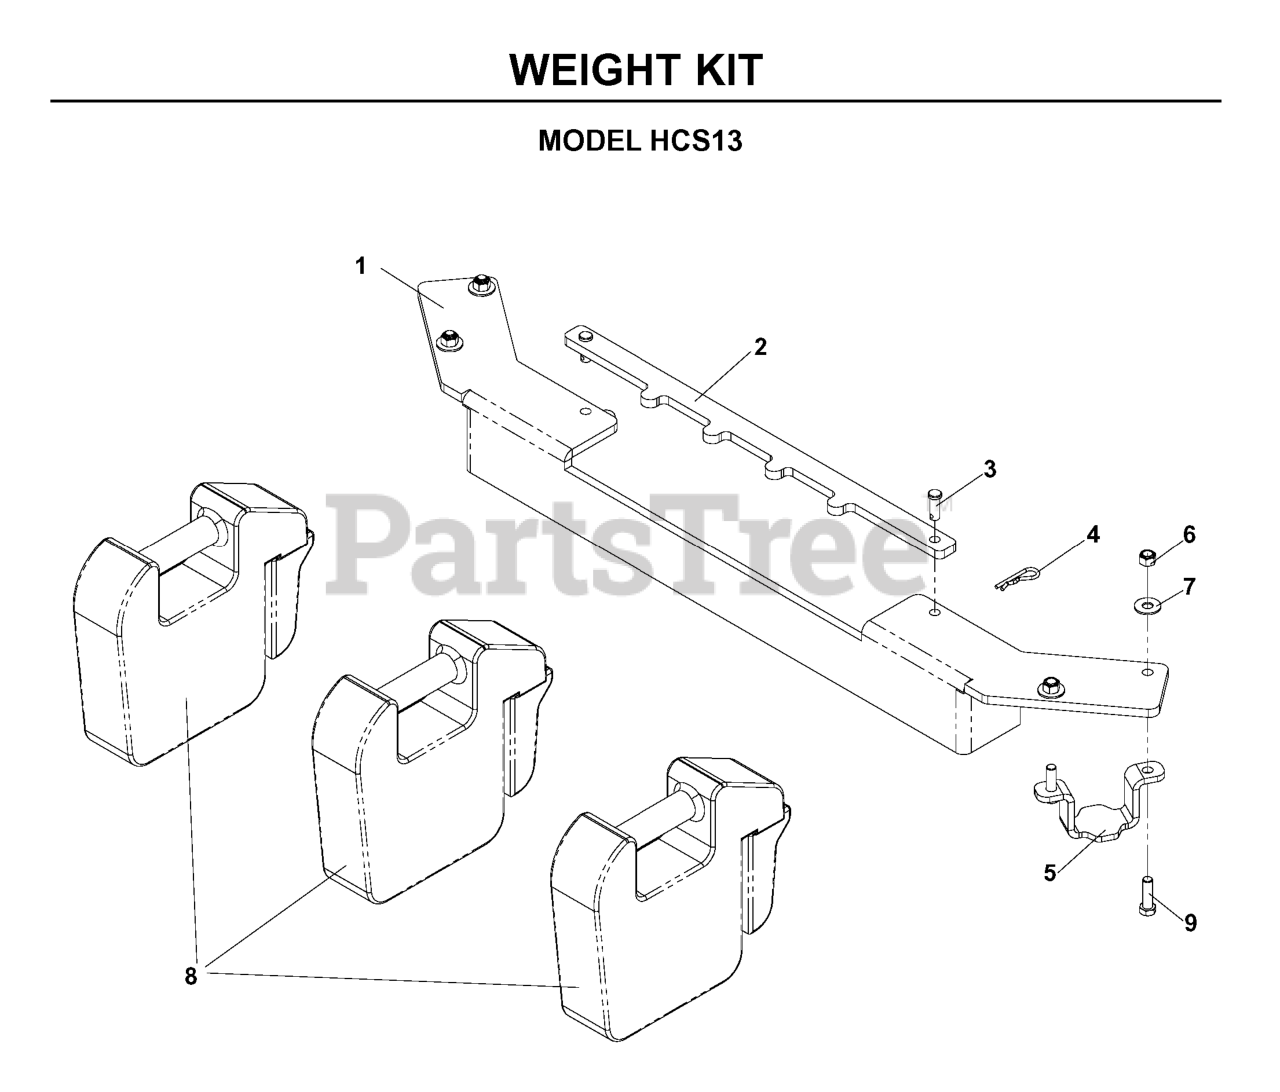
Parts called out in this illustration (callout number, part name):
1	FRONT WT BAR, BLACK
2	HOLD DOWN, WEIGHT BAR
3	CLEVIS PIN
4	RETAINER SPRING
5	WEIGHT KEEPER
6	NUT 3/8-16 NYLOC
7	WASHER 3/8 FLAT
8	CAST COUNTERWEIGHT
9	HCS 3/8C X 1 1/4 GR5
